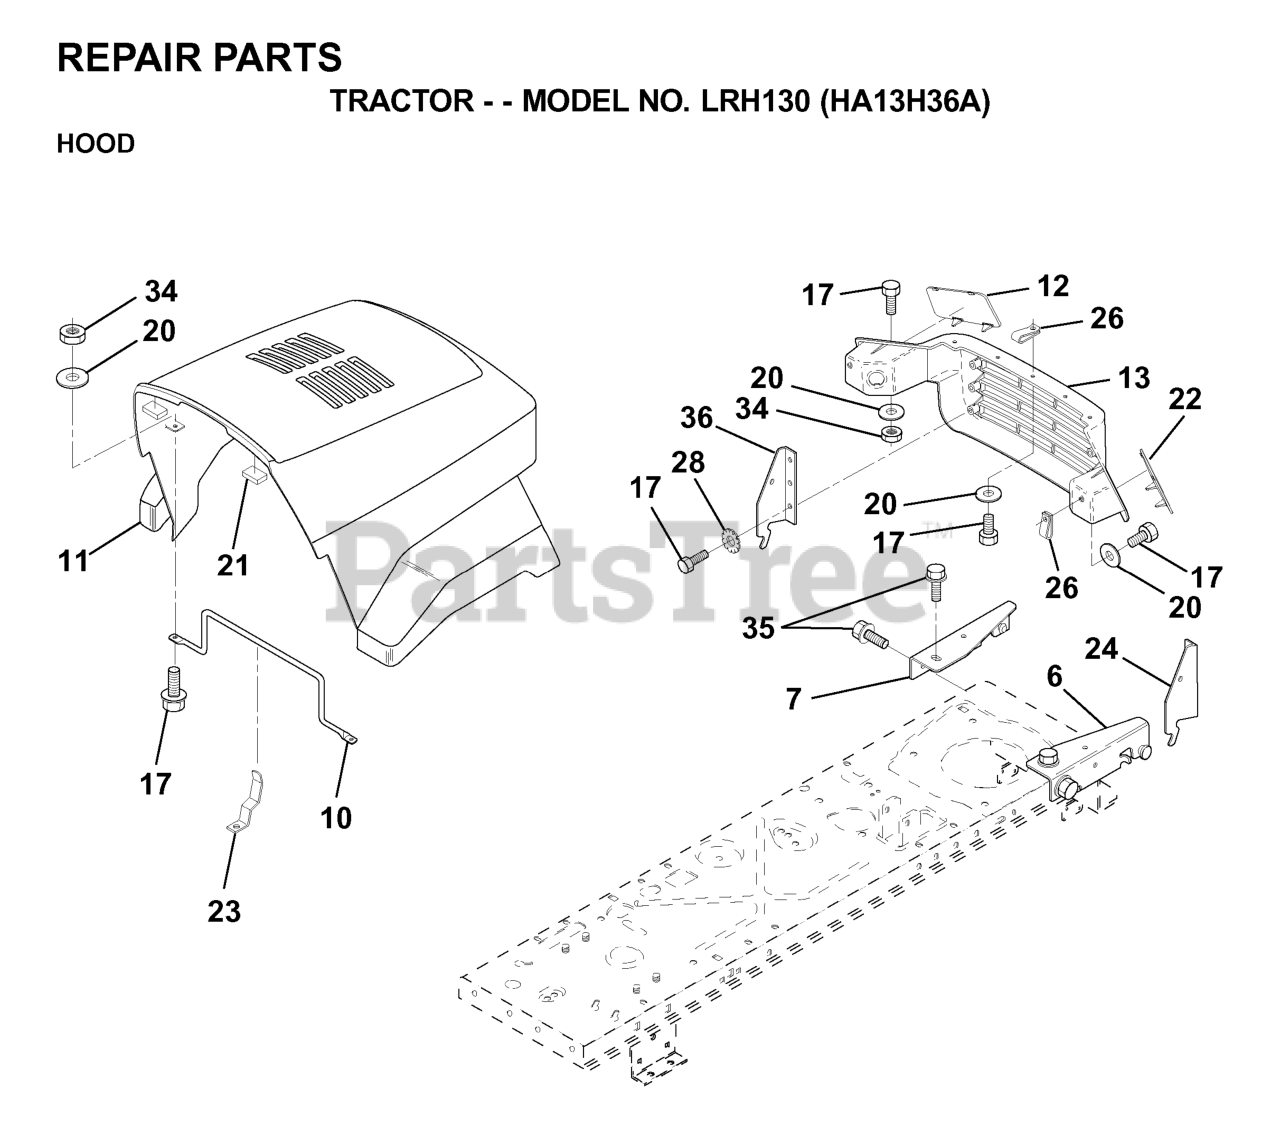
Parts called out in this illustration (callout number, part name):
6	BRACKET ASSY HOOD
7	BRACKET ASSY
10	BRACE HOOD
11	HOOD
12	LENS/LH
13	GRILLE
17	BOLT
21	BUMPER HOOD T
22	LENS
23	HOOD LATCH
24	BRACKET PIVOT
26	CLIP TINNERMAN
28	Washer, Lock, External Tooth 1/4
34	NUT.CROWNLOCK.1/4
35	SCREW.THDROL.5/16-18X3/4.TTY
36	BRACKET HOOD
